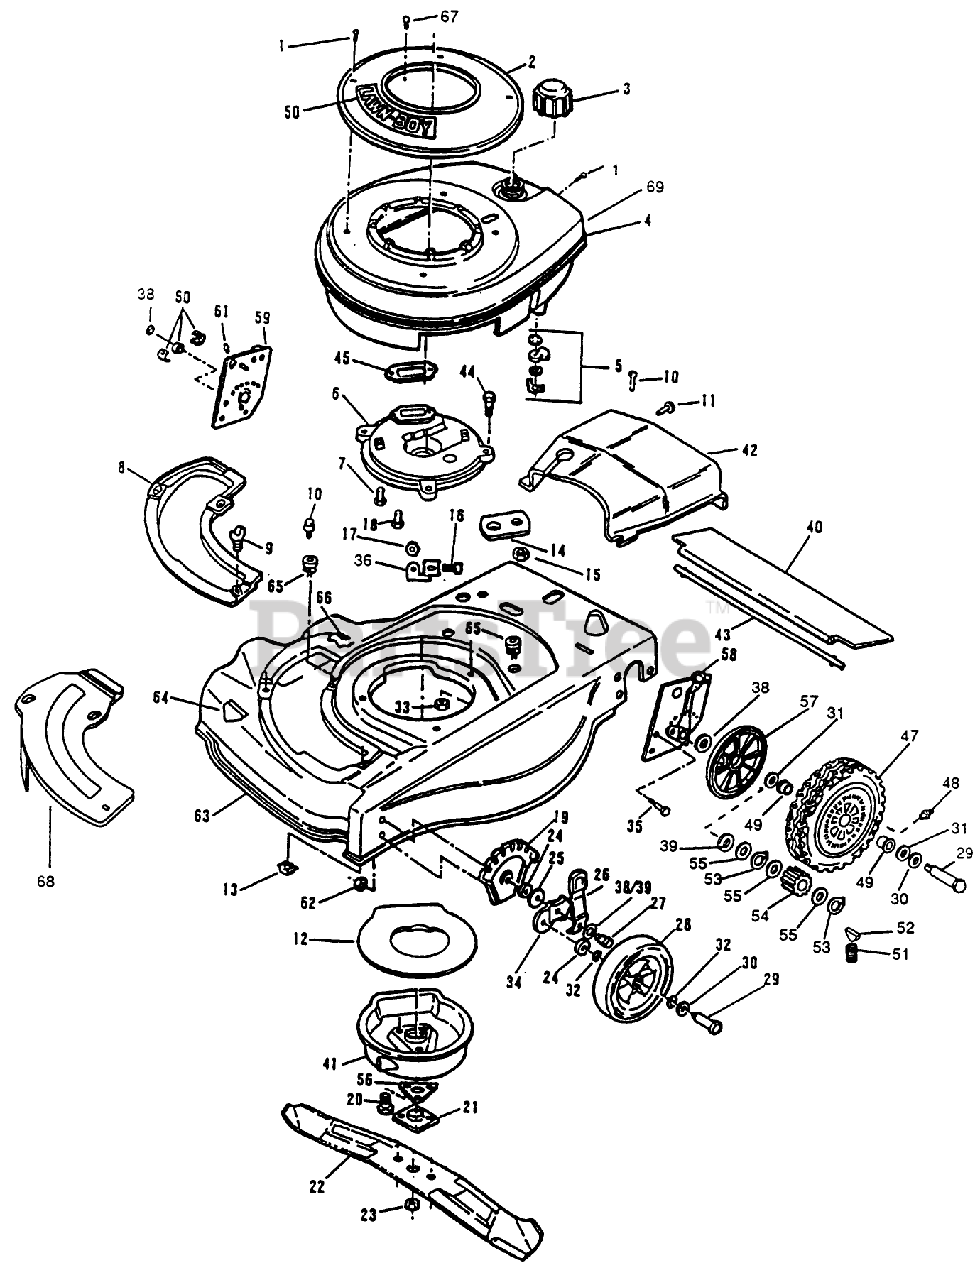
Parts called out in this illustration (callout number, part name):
1	SCREW - SELF TAPPING
3	FUEL CAP & INSERT
4	SHROUD,TANK&VAL
5	SHUT OFF VALVE KIT
7	SCREW V
9	WING SCREW LAWRE
11	SCREW
12	BAFFLE,MUFFLER S
13	NUT-CAGE
14	BOLSTER PLATE LB
15	LOCKNUT E
17	LOCKNUT E
19	PLATE HGT ADJ TRO
20	SCREW
21	PLATE AND COLLAR ASM
23	NUT-BLADE
24	WASHER WROUGHT
25	WASHER
26	KNOB&SPRING FORMCO
27	BOLT
29	BOLT WHEEL
30	SPACER
31	WASHER-FELT
32	WASHER
33	NUT-LOCK F
38	WASHER
39	WASHER
40	SHIELD-TRAILING
44	SCREW-HH
46	NUT-LOCK F
48	FITTING LINCOLN
51	SPRING
52	KEY
53	RET RING
54	PINION BROCKWAY
55	SPACER/GR ALGHNY
56	SUPPORT F
58	HEIGHT ADJ. AY.
59	HEIGHT ADJ. AY.
60	REAR AXLE BEARING
61	**FITTING LINCOLN
62	LOCKNUT
63	HSG AY-21"
67	SCREW SEMS SM
